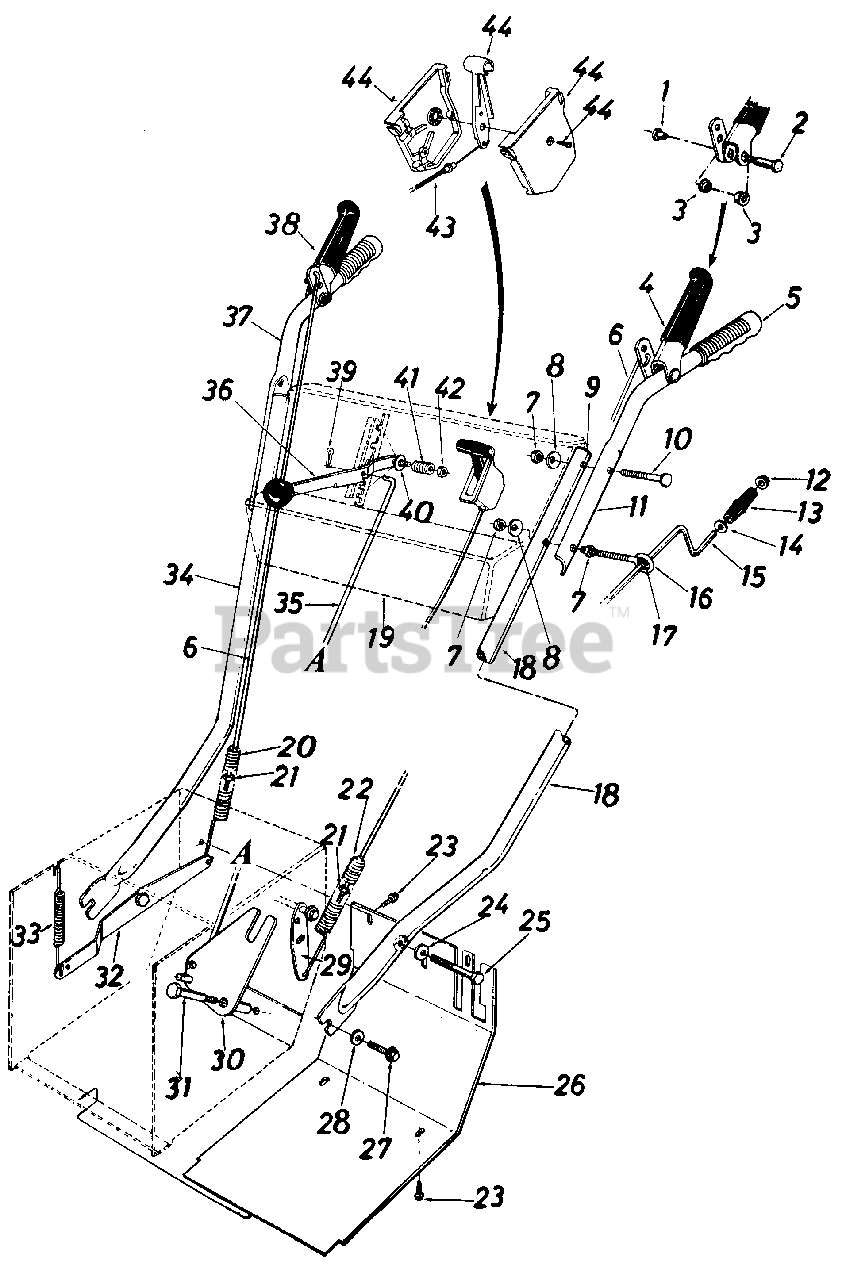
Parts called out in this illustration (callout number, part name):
1	Shld. Nut 1/4-20 Thd.
2	Shld. Bolt .374 Dia. x 1.53" Lg.
3	Hex Flange Plastic Bearing .38" I.D.
4	Clutch Grip Ass'y.-L.H.
5	Grip
6	Lockout Rod
7	Hex Nut 5/16-18 Thd.
8	Bell-Wash. .341" I.D. x .88" O.D.
9	Plastic Plug
10	Curved Carriage Bolt 5/16-18 x 2.0" Lg.
11	Upper Handle-L.H.
12	Push Nut 3/8" Rod
13	Knob 3/8" Rod
14	Fl-Wash. .40" I.D. x .62" O.D.
15	Chute Crank Ass'y.
16	Eye Bolt 5/16-18 x 5.0" Lg.
17	Grommet
18	Lower Handle-L.H.
19	Handle Panel Ass'y.
20	Extension Spring .75" O.D. x 5.0" Lg.
21	Hex Ins. L-Nut 1/4-20 Thd.
22	Extension Spring .75" O.D. x 5.0" Lg.
23	Hex Wash. Hd. Self-Tap Scr. 5/16-24 x .50" Lg.
24	Bell-Wash. .40" I.D. x .88" O.D.
25	Hex Bolt 3/8-16 x 2.0" Lg.
26	Frame Cover
27	Pilot Hex Scr. 3/8-16 x .88" Lg.
28	Bell-Wash. .40" I.D. x .88" O.D.
29	Drive Clutch Brkt. Ass'y.
32	Auger Clutch Brkt.
33	Extension Spring .38" O.D. x 3.18" Lg.
34	Lower Handle-R.H.
35	Shifting Rod
36	Shift Handle Ass'y.
37	Upper Handle-R.H.
38	Clutch Grip Ass'y.-R.H.
39	Int. Cotter Pin 5/16" Dia.
40	Bell-Wash. .40" I.D. x .88" O.D.
41	Compression Spring
42	Hex Ins. L-Nut 3/8-24 Thd.
43	Throttle Wire 26"-Black
44	Throttle Contral Box Ass'y.
